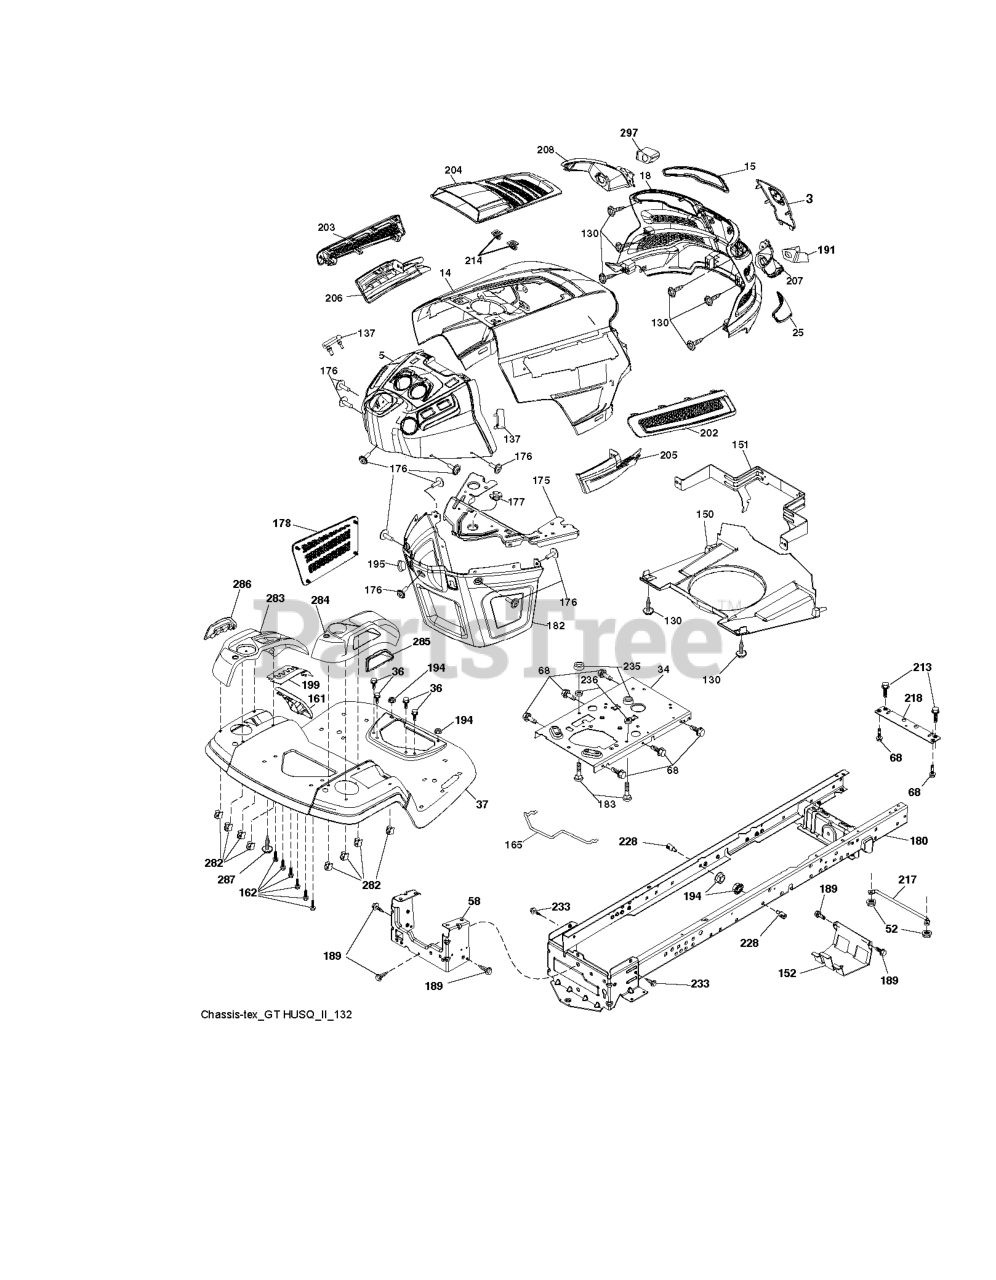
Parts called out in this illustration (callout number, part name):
3	APPLIQUE.SUBASM.GT.HUSQ.II
5	DASH.UPR.ASSY.GT2.SRVMNDER.PTO
14	HOOD.ASM.HUSQVARNA.GT.TEX.ORAN
15	LENS.HEADLIGHT.LH.GTII.2011
18	GRILLE.SUBSTRATE.2011.
25	LENS.HEADLIGHT.RH.GTII.2011
34	PLATE.ENGINE.WELDED.CHASSIS
36	SCREW 5/16"
37	FENDER.TLT.FS.W/CPH/FW/RSF.668
52	LOCKNUT
58	DRAWBAR UPPER 2PC SMALL FENDER
68	Screw 5/16-18 x 1/2 Hex, Self Tapping 5/16-18 x 1/2
130	SCREW.#10 X 0.750.BOS
137	BUMPER DASH
150	AIR.DUCT.GTV.BLACK
151	BRACKET.PIVOT.HOOD.GT.HUSQ.II
152	SHIELD.BROWNING.W/TEX
161	WINDOW.FUEL.LT.HUSQ.TEX.498
162	SCREW.HI-LO.CONSOLE
165	SUPPORT.TANK.REAR.W/TEX
175	PLATE.CROSSMEMBER.HUSQ
176	SCREW.#10-24X5/8.RN.QU
177	BUSHING, STEERING
178	CARGO.ASM.NET.TXGT.W/C
180	CHASS.WLDMNT.TL.12GA/2P.48/54
182	DASH.LOWER.COMMON.12V.ADAPTOR
183	BOLT.5/16-18X1-1/4 FULL THD
189	SCREW
191	INSERT.REFLECTIVE.RH.HUSQ.GTII
194	NUT LOCK HEX FLANGE 5/16-18
195	PLUG.HOLE.DASH.LOWER.12V.BLK
199	PLATE.DECK.LIFT.HUSQ.LT
202	VENT.SIDE.RH.GT.HUSQ.II.
203	VENT.SIDE.LH.GT.HUSQ.II.498
204	VENT.TOP.HUSQ.GT2
205	SIDE.TRIM.RH.GT.HUSQ.II
206	SIDE.TRIM.LH.GT.HUSQ.II.GRAY
207	BEZEL LIGHT.RH.GT.II.MYLAR
208	BEZEL LIGHT.LH.GT.II.MYLAR
213	BOLT
214	CLIP.RETAINER.TINNER.
217	ROD.PIVOT.HOOD
218	X-PIECE.HOOD.STOP.NON/
228	STUD.FASTNER.W/ANTI-ROTATE
233	BOLT.SHOULDER
235	SPACER FENDER
236	NUT.CENTERLOCK.5/16-
282	CLIP.RETAINER.CONSOLE.LT.HUSQ
283	CONCOLE.CNTRL.PDL.HUSQ.LT.498
284	CONSOLE.DECK.LIFT.R.SDFL.HUSQ
285	CONSOLE INSERT RH
286	CONSOLE.INSRT.LH.HUSQ.LT.BLACK
287	SCREW 1/4X20
297	INSERT.REFLECTIVE.LH.HUSQ.GTII
